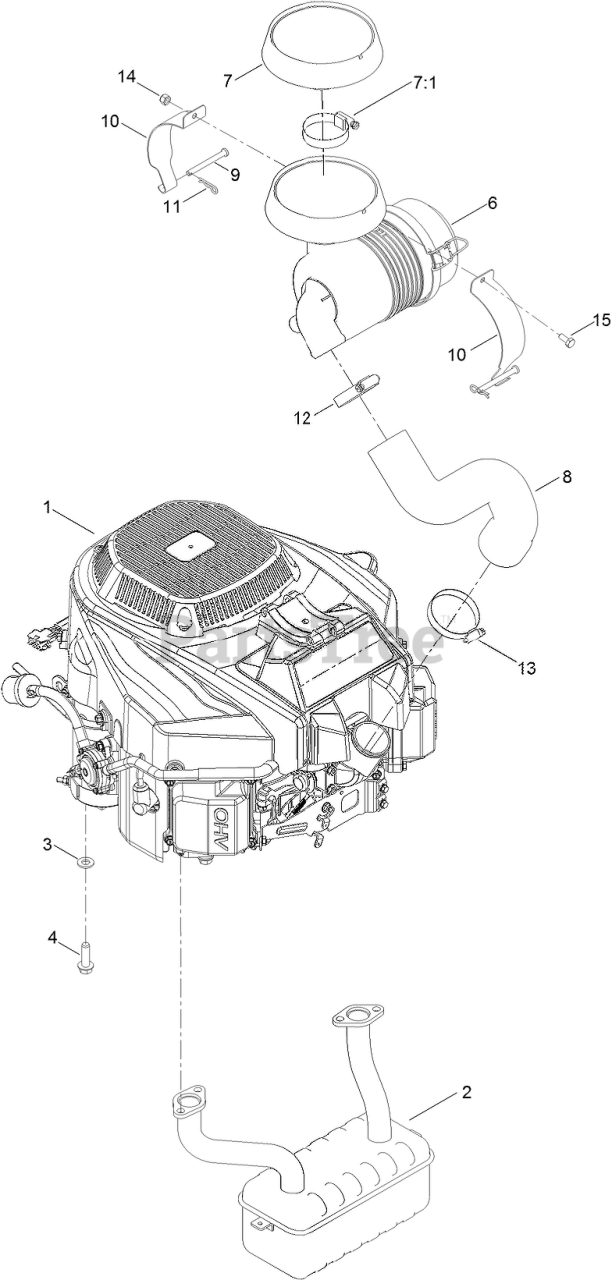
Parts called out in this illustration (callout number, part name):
1	ENGINE-2P77F-HD
2	MUFFLER
3	WASHER-FLAT
4	SCREW-THD
6	AIR CLEANER ASM
7	RAIN CAP KIT
7:1	CLAMP-HOSE
8	HOSE-INTAKE
9	PIN-CLEVIS
10	STRAP-CANISTER, AIR
11	PIN-COTTER
12	CLAMP-HOSE
13	CLAMP-HOSE
14	NUT-HEX
15	SCREW-HH
